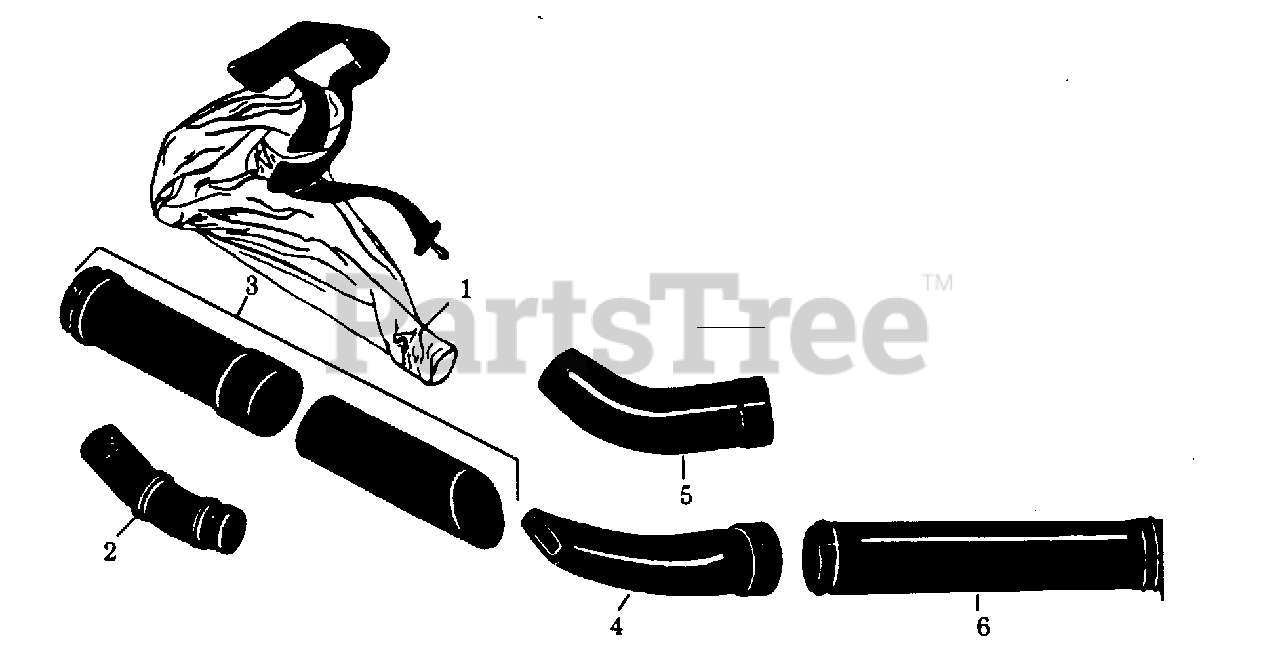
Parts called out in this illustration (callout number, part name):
1	Collection Bag W/Strap
2	Collection Bag Elbow Tube
3	Vacuum Tube
4	Blower Nozzle--Flare
5	Blower Nozzle--Concentrator
6	Blower Tube
